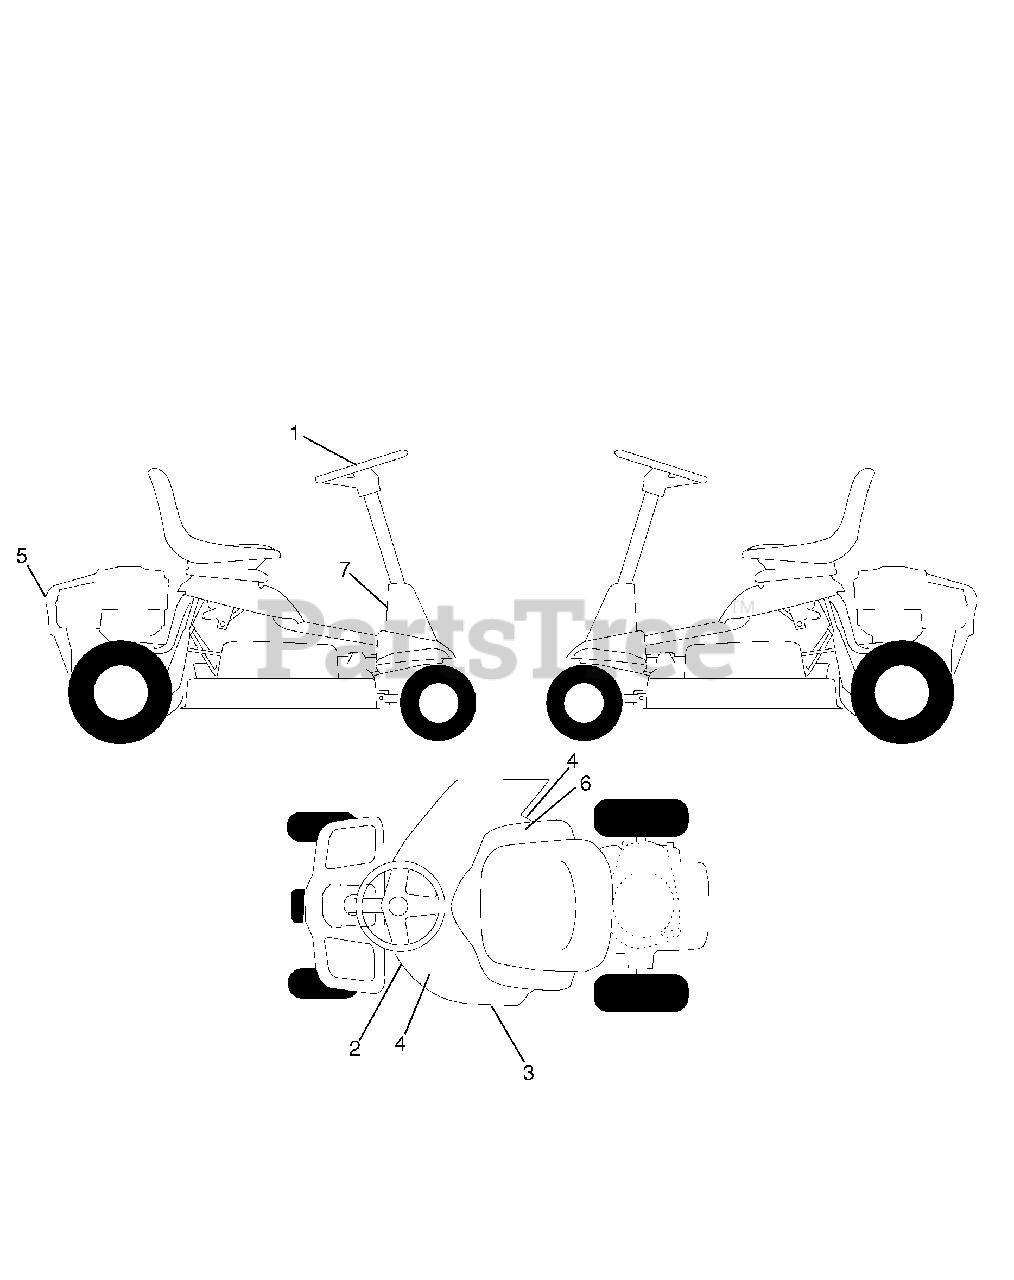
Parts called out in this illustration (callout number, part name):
1	Steering Wheel Decal
2	Decal, V-Belt Sch 30"
3	Decal, Warning Deflector Cut Finger
